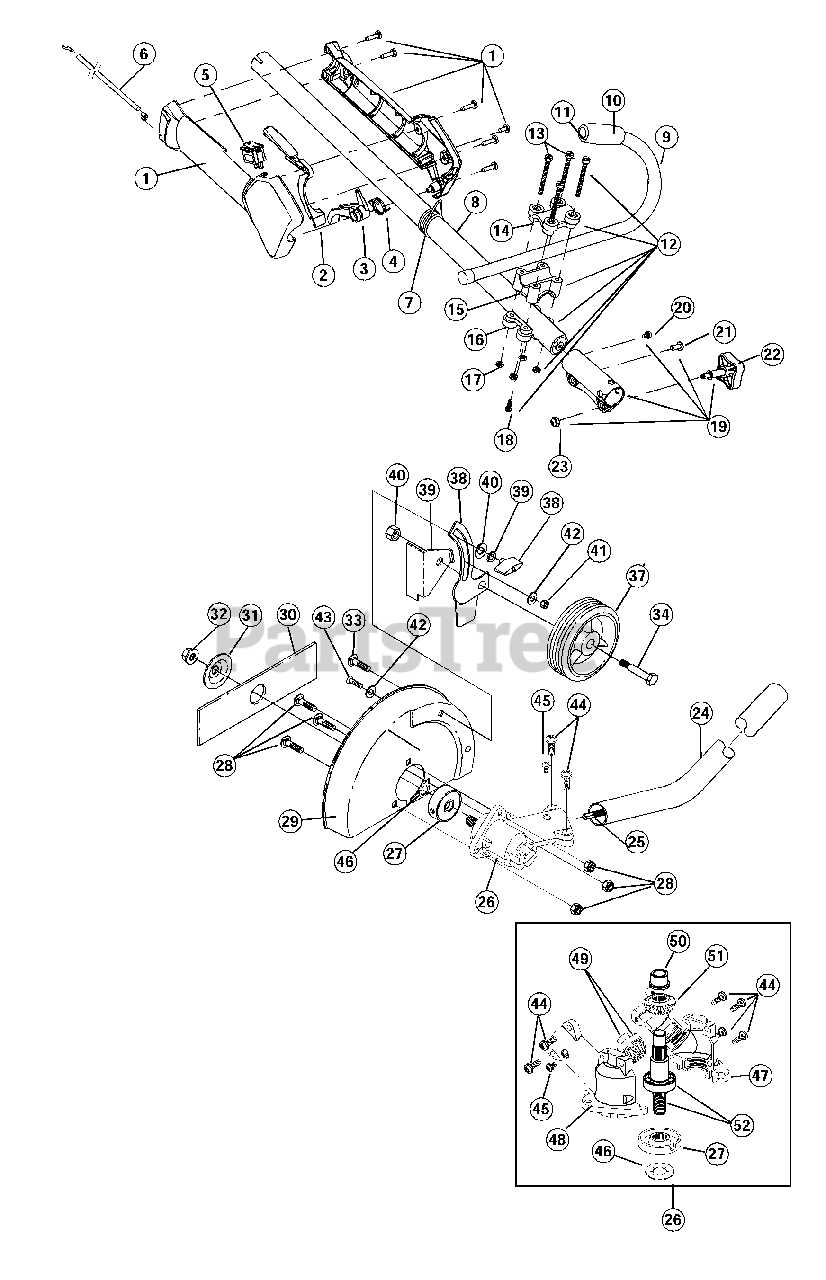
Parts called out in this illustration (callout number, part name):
1	Throttle Housing and Trigger Assembly
2	Throttle Trigger Lock-Out
3	Throttle Trigger
4	Throttle Trigger Spring
6	Throttle Cable
7	Harness Clip
8	Upper Drive Shaft Housing Assembly
9	J-Handle Assembly
11	Tube Closure
12	Handle Bracket Assembly
14	Upper Handle Clamp
15	Middle Handle Clamp
16	Lower Handle Clamp
18	Anti-Rotation Screw
19	Split Boom Link Coupler
22	Adjustment Knob
23	Knob Retaining Nut
24	Drive Shaft Housing Assembly
25	Drive Shaft Assembly
26	Gearbox Assembly
28	Shield Mount Screw
29	Blade Shield
30	Edger Blade
31	Retaining Washer
32	Lock Nut
33	Shoulder Bolt
34	Wheel Mounting Hardware
35	Deflector
36	Guide Bracket
38	Adjustment Knob
39	Lock Washer
41	Locknut
44	Gearbox Mounting Hardware
45	Anti-Rotation Screw
46	Palnut
47	Left Housing
48	Right Housing
49	Pinion Gear Assembly
50	Output Shaft Bushing
51	Output Shaft Gear
52	Output Shaft Assembly
